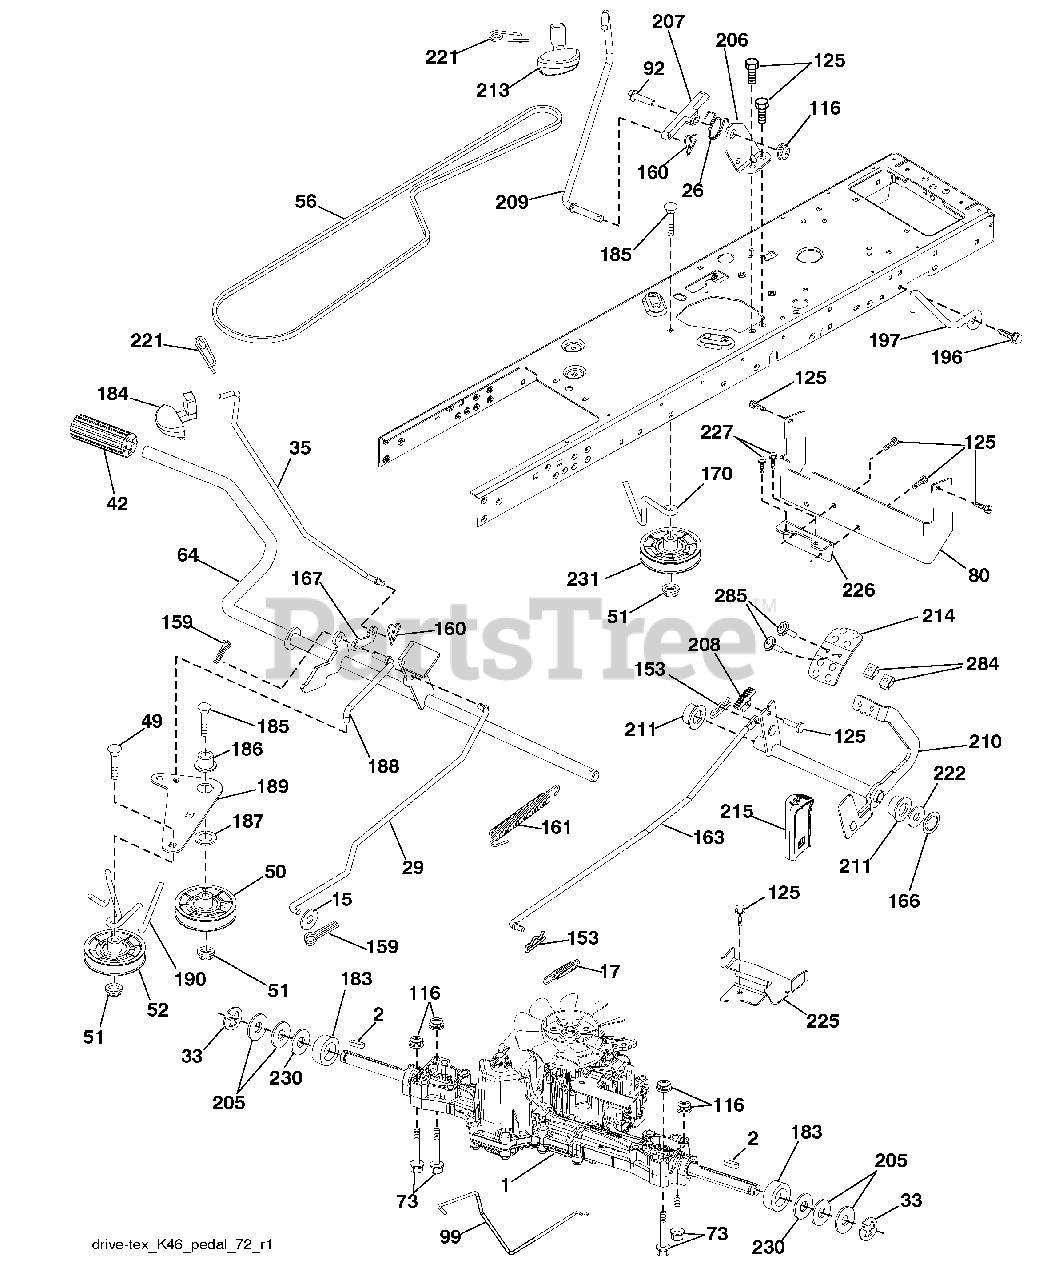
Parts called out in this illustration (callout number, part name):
15	Washer 13/32 x 13/16 x 16 Ga.
17	Spring, Brake
26	Spring Return Cruise
29	Rod, Brake
35	Rod, Brake, Park
42	Cover, Foot Pedal
50	Pulley Idler Flat
51	Lock Nut 3/8-16
52	Idler V-Groove 910" Offset
56	V-Belt, Drive
64	Shaft Asm. Pedal Brake Control
73	Bolt Hex Flghd 5/16-18 Gr. 5
80	Bracket Strap Torque
92	Bolt Fin Hex 5/16-18 unc x 1.25
99	Rod Spring Bypass
116	Nut Lock Hex Flange 5/16-18
125	Screw 5/16-18 x 3/4
153	Retainer Spring
159	Pin Cotter 1/8 x 3/4
160	Retainer Clip
161	Spring, Return, Clutch
163	Rod Pedal Control
167	Latch Brake Parking
170	Keeper Belt Centerspan
183	Spacer Split
184	Handle Parking Brake
185	Bolt Rdhd Sqnk 3/8-16 x 2-1/2
186	Spacer Retainer
187	Washer
188	Link Clutch Ground Drive
189	Bellcrank Ground Drive
190	Keeper Bellcrank Ground Drive
196	Screw 3/8-16 x 1
197	Bracket Clutch Anti-Rotation
206	Bracket Mount Latch Cruise
207	Latch Control Cruise
208	Gear Sector Control Cruise
209	Rod Control Cruise
210	Rocker Asm. Pedal Control
211	Bearing Nylon
213	Knob Control Cruise
214	Pedal Forward
215	Pedal Reverse
221	Retainer Spring Clip Handle
222	Washer 21/32 x 1-1/4 x 10 Ga.
225	Keeper Belt Trans.
226	Bracket Mount Torque
227	Screw 5/16-18 x 3/4
230	Washer Hardened
231	Idler V-Groove
284	Nut U-CHNL 1/4-20 550DP .350 PNL
285	Screw PHD 1/4-20 Box Drive
